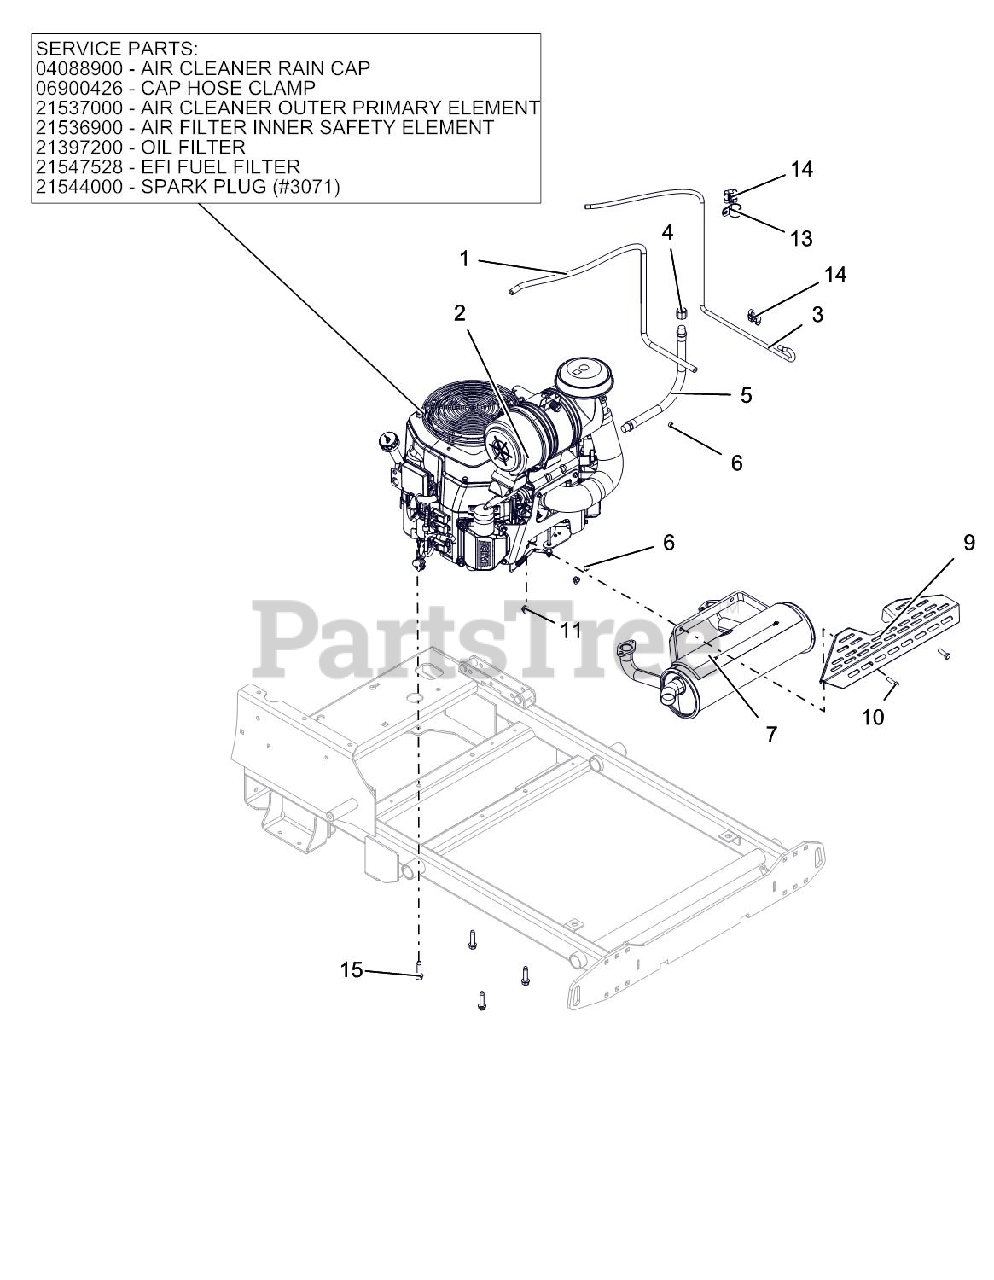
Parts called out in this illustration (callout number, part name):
1	.25 LOW PERM GAS HOSE
2	ENGINE, KOHLER EFI ECV740
2	AIR CLEANER RAIN CAP
2	CAP HOSE CLAMP
2	AIR CLEANER OUTER PRIMARY ELEMENT
2	AIR FILTER INNER SAFETY ELEMENT
2	OIL FILTER
2	EFI FUEL FILTER
2	SPARK PLUG
3	HOSE, .188 LOW-PERM BULK GAS
4	PIPE, CAP 3/8 NPT FEMALE
5	HOSE, HYD .38-11-OK M6N0-M6N0
6	CLAMP - HOSE, SPRING .188
7	MFLR, KOHLER
9	GUARD, HEAT SHIELD (BLACK)
10	BLT-HEX .31-18X1.00 GR5 YWZC
11	NUT-LK-NYL-FLG .31-18 YWZC
13	CLAMP, CUSHIONED STEEL REV
14	CLIP, T, .38-.50
15	SCR-TAP .38-16X1.50 HWH TR YZ
